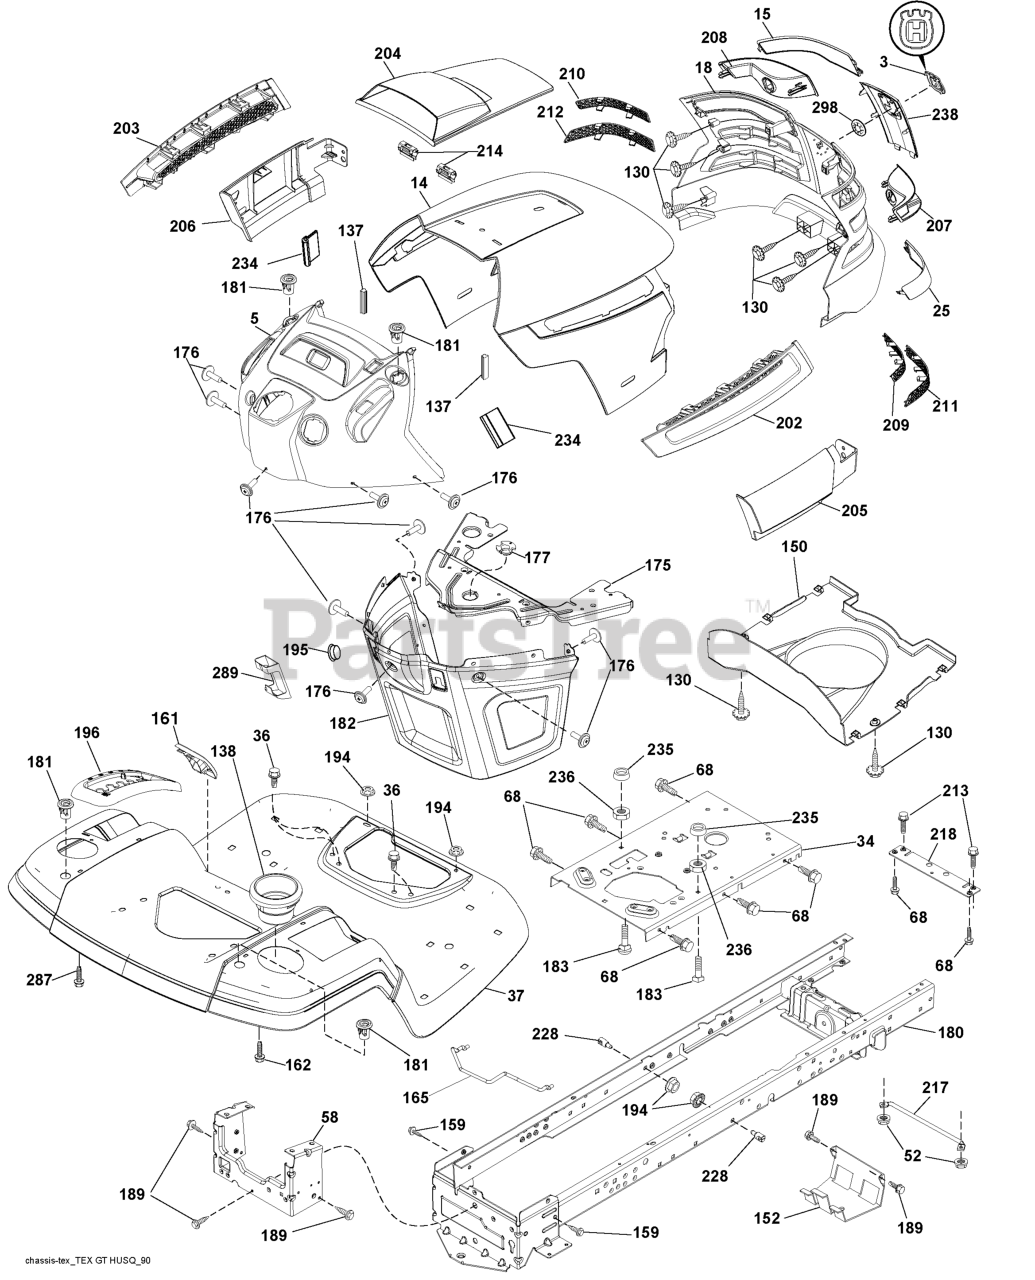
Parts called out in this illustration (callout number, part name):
3	RP LOGO
5	DASH.ASM.HUSQ.GT.CC.N/GA.N/C
14	HOOD
15	LENS.LH.TEX.GT.HUSQ.CL
18	GRILL.ASM.HUSQ.TG/CRD.W/TRIM
25	LENS.RH.TEX.GT.HUSQ.CL
34	PLATE.ENGINE.WELDED.CHASSIS
36	SCREW 5/16"
37	FENDER.TLT.FS.W/CPH/FW/RSF.ORN
52	LOCKNUT
58	DRAWBAR UPPER 2PC SMALL FENDER
68	Screw Thdrol 5/16-18 X 1/2
130	SCREW.#10 X 0.750.BOS
137	BUMPER DASH
138	CUPHOLDER.TL.TEX.418
150	AIR.DUCT.TEXGT.HUSQ.31
152	SHIELD.BROWNING.W/TEX
159	SCREW, 3/8-16X3/4
161	RP WINDOW.FUEL.LT.TEX.GREY
162	SCREW.HI-LO.CONSOLE
165	SUPPORT.TANK.REAR.W/TEX
175	PLATE.CROSSMEMBER.HUSQ
176	SCREW.#10-24X5/8.RN.QU
177	BUSHING, STEERING
180	CHASS.WLDMNT.TL.12GA/2P.48/54
181	BUSHING.MNT.FEND.CRGO.
182	DASH.LOWER.COMMON.12V.ADAPTOR
183	BOLT.5/16-18X1-1/4 FULL THD
189	SCREW
194	NUT LOCK HEX FLANGE 5/16-18
195	PLUG.HOLE.DASH.LOWER.12V.BLK
196	RP CONSOLE.ASM.DECKLFT.GR/RBT.
202	VENT.SIDE.HOOD.HUSQ.RH.GREY
203	VENT.SIDE.HOOD.HUSQ.LH.GRAY
204	HOOD VENT
205	SKIRT.HOOD.SIDE.HUSQ.RH.GREY
206	SKIRT.HOOD.SIDE.HUSQ.LH.GREY
207	BEZEL.RH.TEX.GT.HUSQ
208	BEZEL.LH.TEX.GT.HUSQ
209	INSERT.HEX.GRILL.HUSQ.GREY
210	INSERT.HEX.GRILL.HUSQ.
211	INSERT.HEX.GRILL.HUSQ.
212	INSERT.HEX.GRILL.HUSQ.
213	BOLT
214	CLIP.RETAINER.TINNER.
217	ROD.PIVOT.HOOD
218	X-PIECE.HOOD.STOP.NON/
228	STUD.FASTNER.W/ANTI-ROTATE
234	BUMPER.HOOD.TEX.HUSQVARNA
235	SPACER FENDER
236	NUT.CENTERLOCK.5/16-
238	TRIM.HUSQ.TG/CRD.SERVICE
287	SCREW 1/4X20
289	PLUG.N/CRUISE.COMMON.YT/GT.BLK
298	NUT PUSH M
